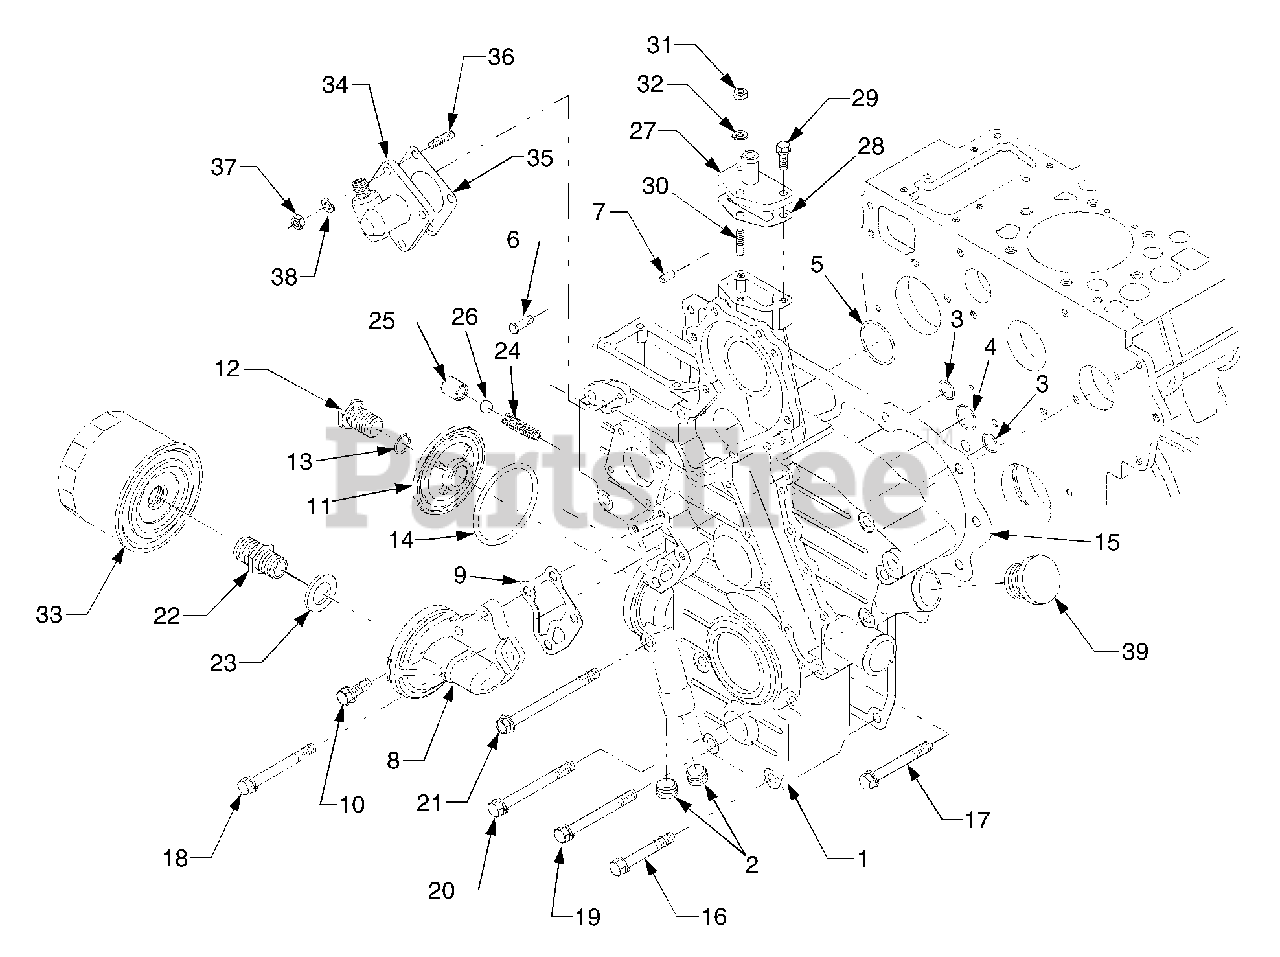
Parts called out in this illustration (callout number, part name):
1	Gear Case Ass'y
6	Pin, Start Spring
7	Pin, Straight
8	Support, Oil Filter
9	Gasket
15	Gasket, Gear Case
23	Washer, Plain
27	Flange, Water Return
32	Washer, Spring
33	Filter, Engine Oil
34	Hour Meter Ass'y
35	Gasket
36	Stud
37	Nut
38	Washer, Spring
39	Plug, Oil
